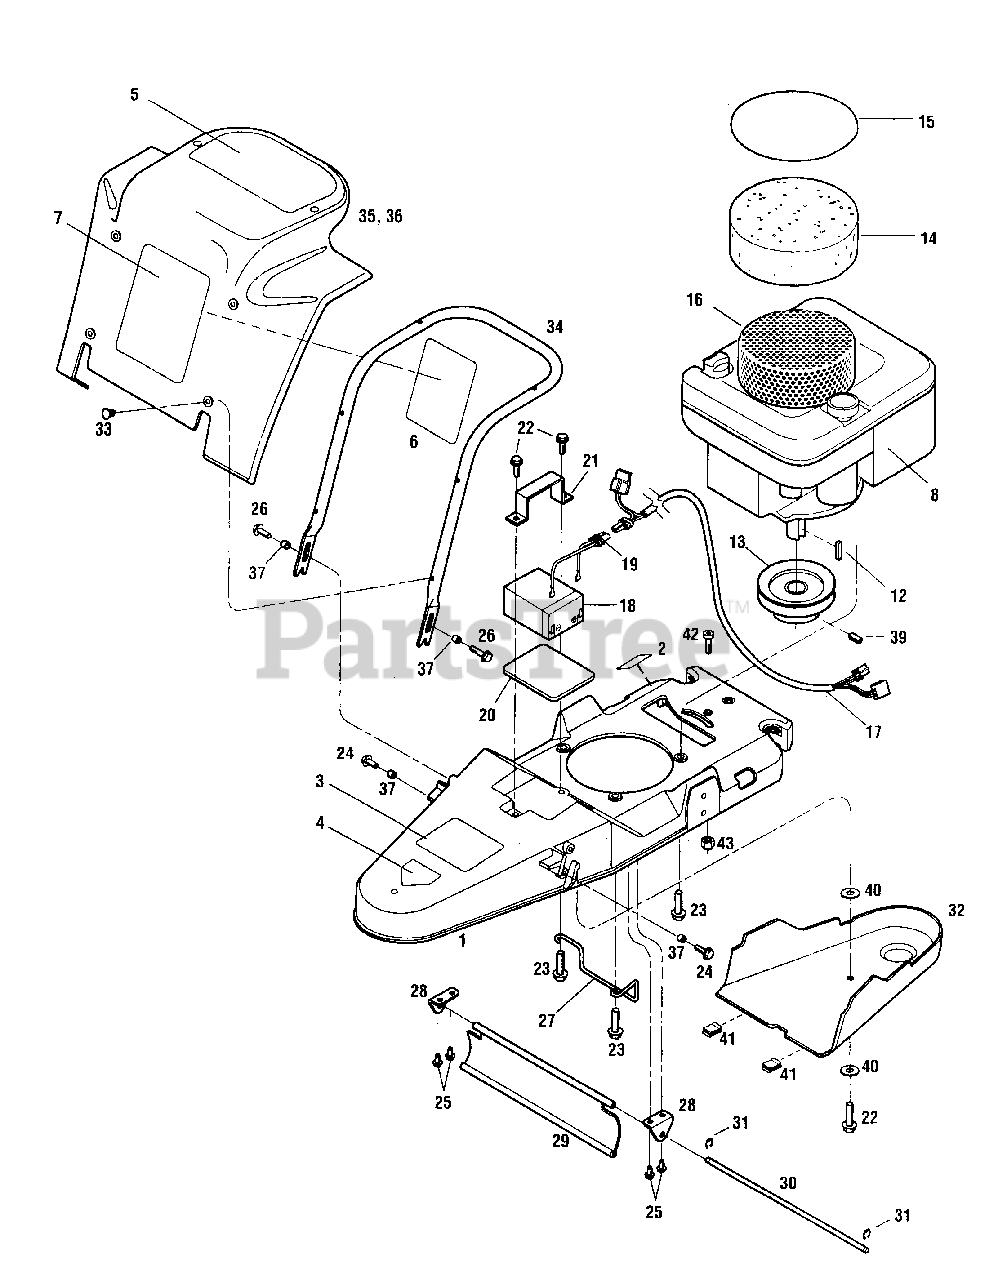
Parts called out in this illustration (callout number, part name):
1	Deck with decals
2	Decal-Hot Surface
3	Decal-Warning/Thrown Objects
4	Decal-Danger Feet/Hands
5	Decal-Engine Cover
6	Decal-Parallel Trim Control
12	Key, 3/16" x 1" Sq
13	Pulley, 4" OD
14	Engine Debris Guard/Foam
15	O-Ring/Engine Debris Guard
16	Engine Debris Guard
17	Wire Harness.
18	Battery.
19	Battery Connector.
20	Battery Pad.
21	Battery Bracket.
22	Hex Hd. Flange Screw, 5/16-18 x 1
23	Hex Hd. Flange Screw, 3/8-16 x 1-1/2
24	Hex Hd. Flange Screw, 1/4-20 x 3/4
25	Hex Hd. Flange Screw, 1/4-20 x 5/8
26	Hex Hd. Flange Screw, 1/4-20 x 1
27	Belt Guide
28	Flap Bracket
29	Deflector Shield
30	Deflector Shield Rod
31	E-Ring, 5/16"
32	Belt Cover
33	Push-In Fastener
34	Engine Cover Support
35	Engine Cover w/decals.
36	Engine Cover w/decals.
37	Spacer
39	Set Screw
40	Washer
42	Socket Hd. Capscrew, 1/4-20 x 1
43	Toplock Nut, 1/4-20
